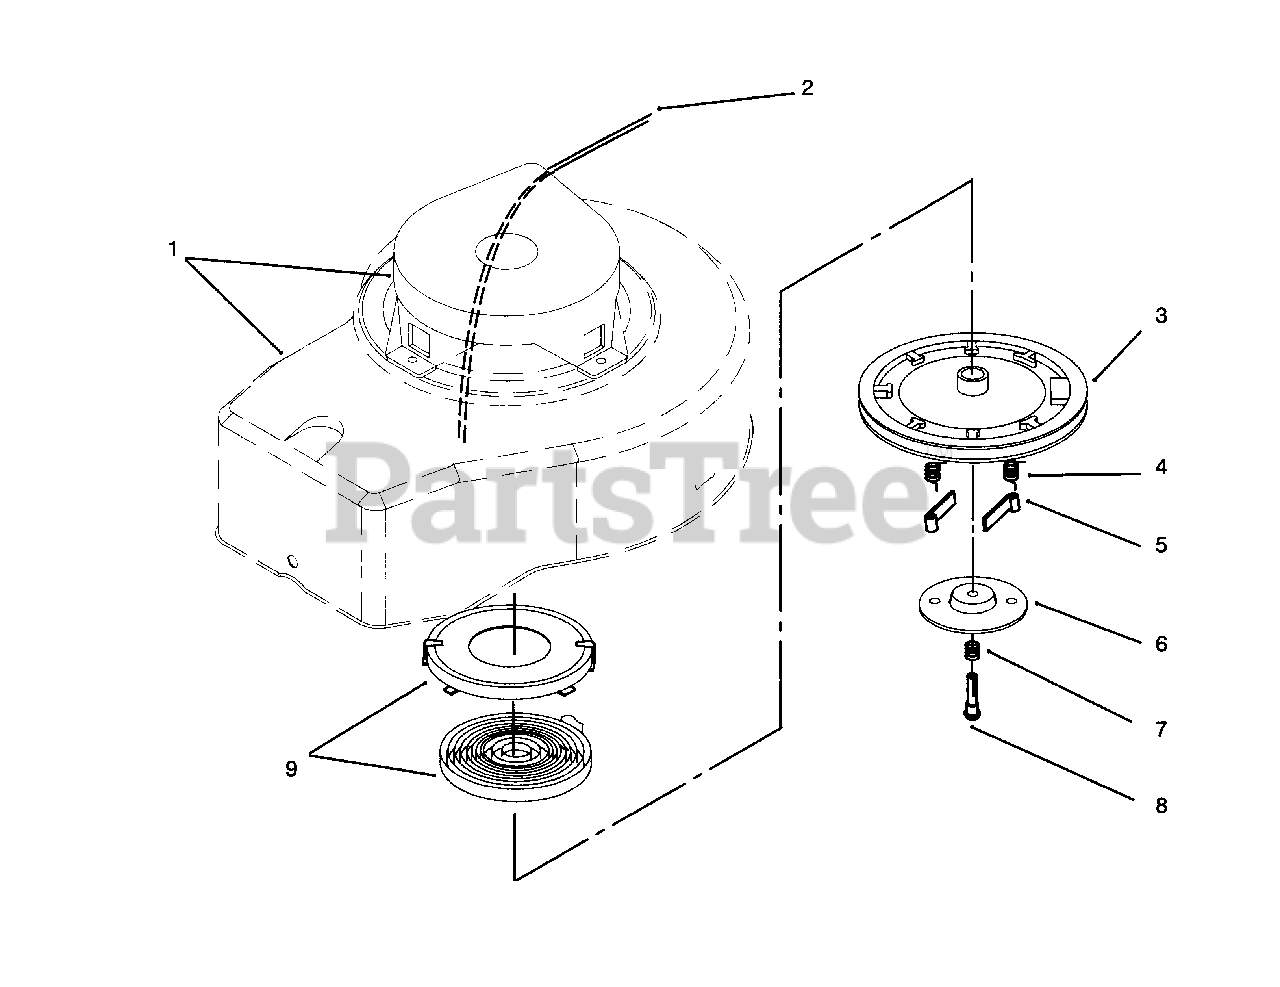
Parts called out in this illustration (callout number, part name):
1	Housing Assembly
2	Rope-Starter
3	Pulley Assembly
4	Spring-Dog
6	Retainer
9	Spring Keeper Assembly
